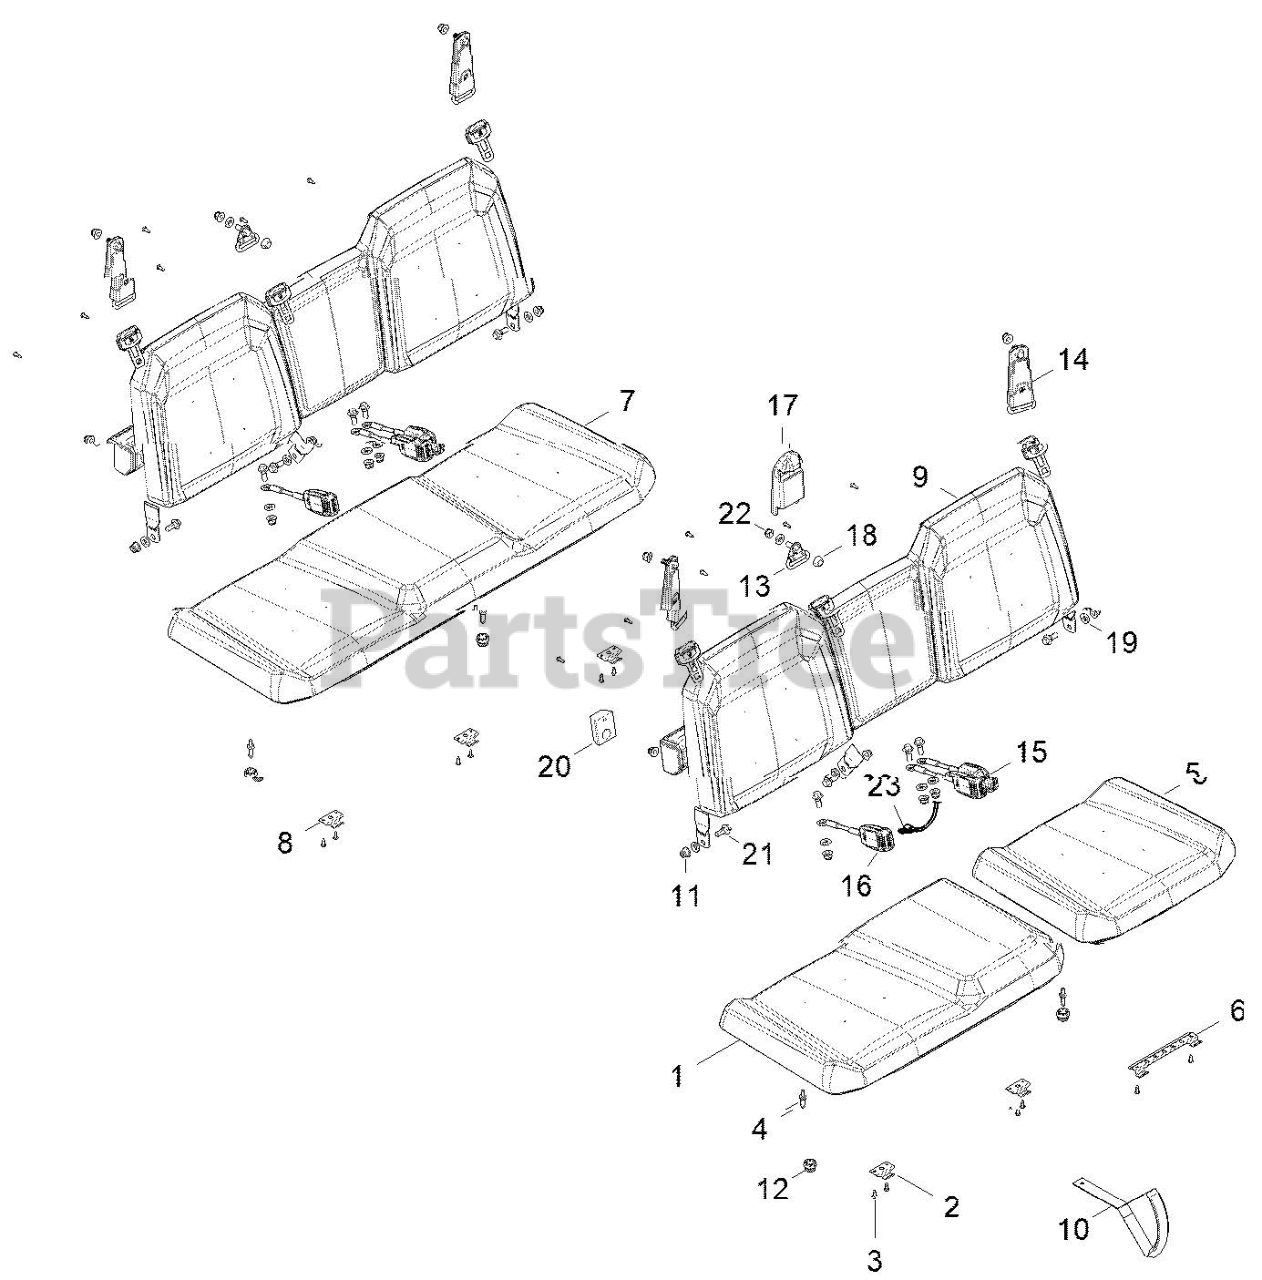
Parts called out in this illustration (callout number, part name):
1	ASM,SEAT,3PASS,BACK,GRVLY,GRAY
2	BRKT-SEAT HINGE
3	SCR-TX TRUSS-#14X3/4,HI/LO ZBK
4	PIN-SEAT LATCH
5	ASM,SEAT,BTM,60,GRVLY GRAY
6	BRKT-SEAT HINGE,DOUBLE
8	BRKT-SEAT HINGE
9	ASM,SEAT,3PASS,BTM,GRVLY GRAY
10	STRAP, SEAT, CENTER
11	NUT-HXFL M12X1.75 NYLOC ZOD
13	ASM-SEAT BELT,3PT,CENTER
14	ASM-SEAT BELT,3PT
15	BUCKLE, SEATBELT, 90, SWITCH
16	BUCKLE-SEATBELT,9.6,PASSENGER
17	COVER-SEAT BELT MOUNT
18	CAP, BOLT HEAD
19	WASHER-SEATBELT,RUBBER
20	PAD-REAR,SEAT BASE
21	SCR-HXFLSH-M12X1.75-M14X9 ZOD
22	NUT-NYLOK,M12X1.5,0600110
23	CLAMP, WIRE, .25 DIA TUBE
